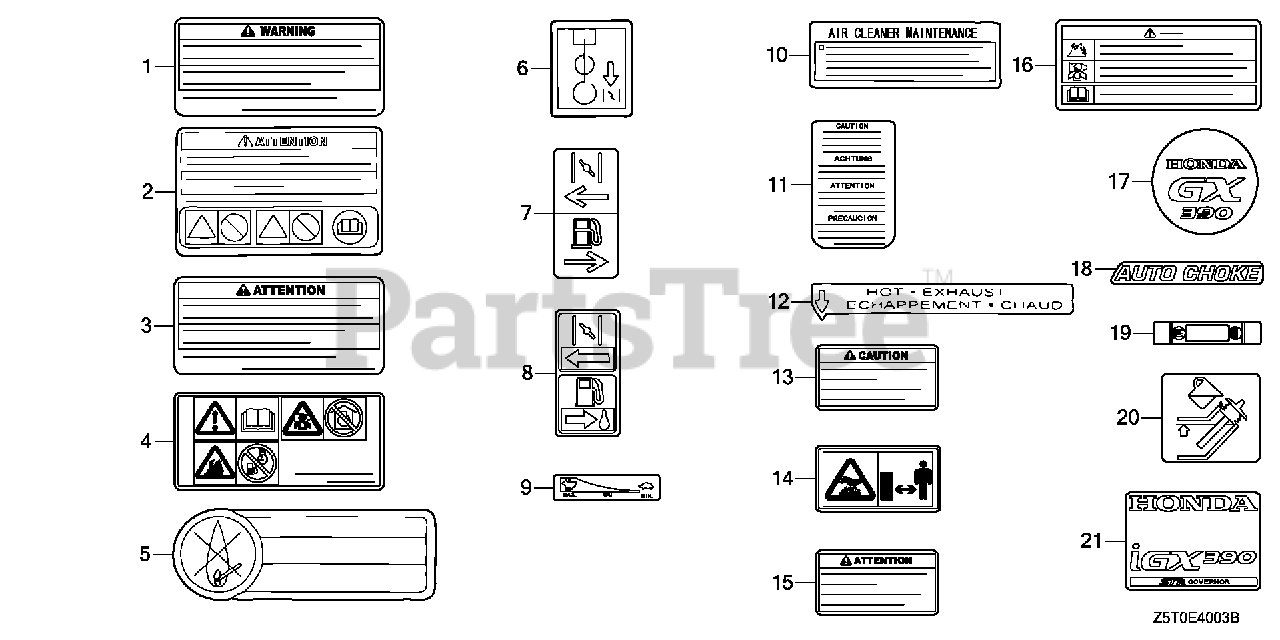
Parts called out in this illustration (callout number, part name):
1	MARK, OPERATOR CAUTION (ENGLISH)(MADE IN THAI)
3	MARK, OPERATOR CAUTION (FRENCH)(MADE IN THAI)
13	MARK, EX. CAUTION (ENGLISH)
15	MARK, EX. CAUTION (FRENCH)
